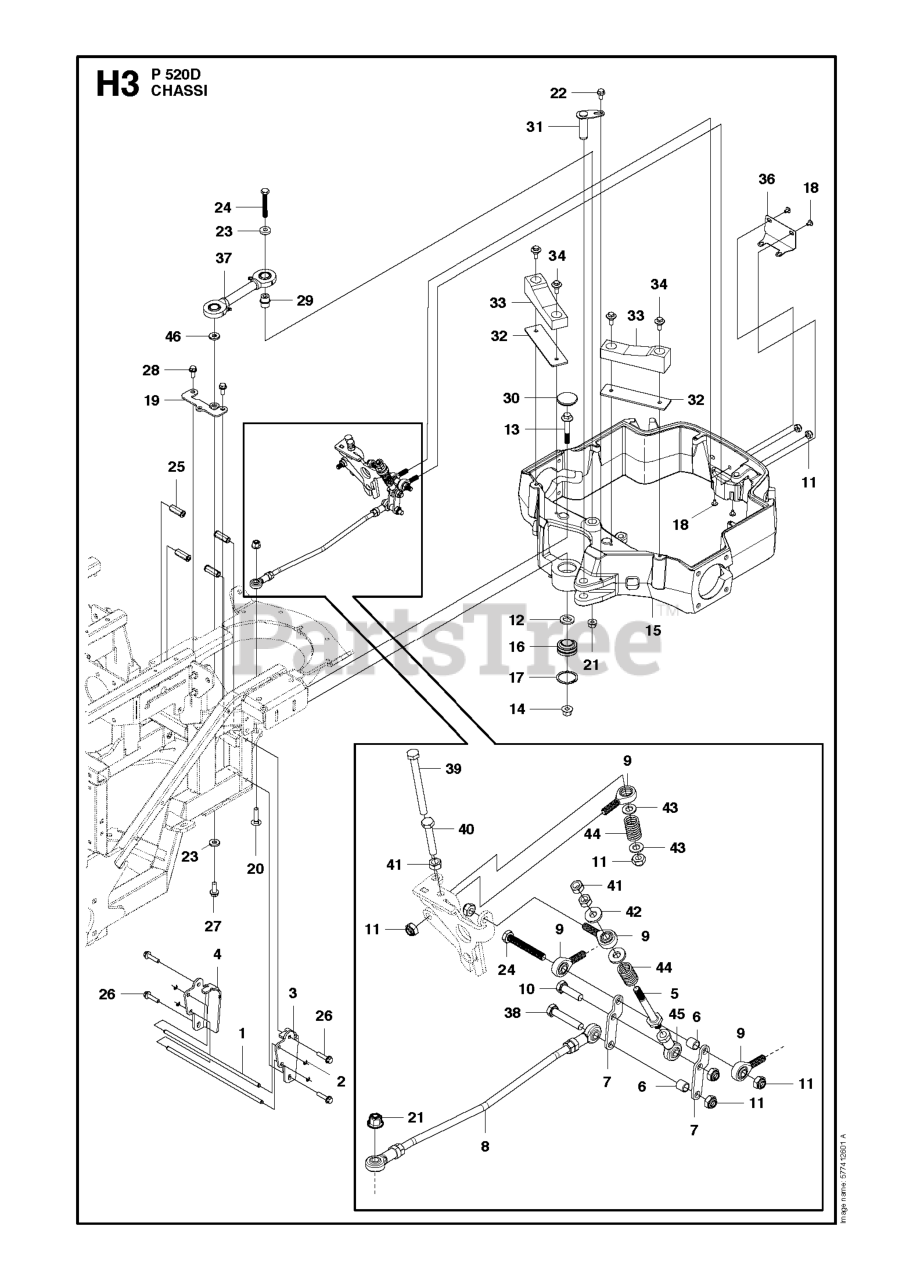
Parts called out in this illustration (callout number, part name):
11	NUT
26	SCREW EHHFM
30	HUB CAP PIVOT WHEEL
34	COLLAR SCREW
41	NUT
43	WASHER
